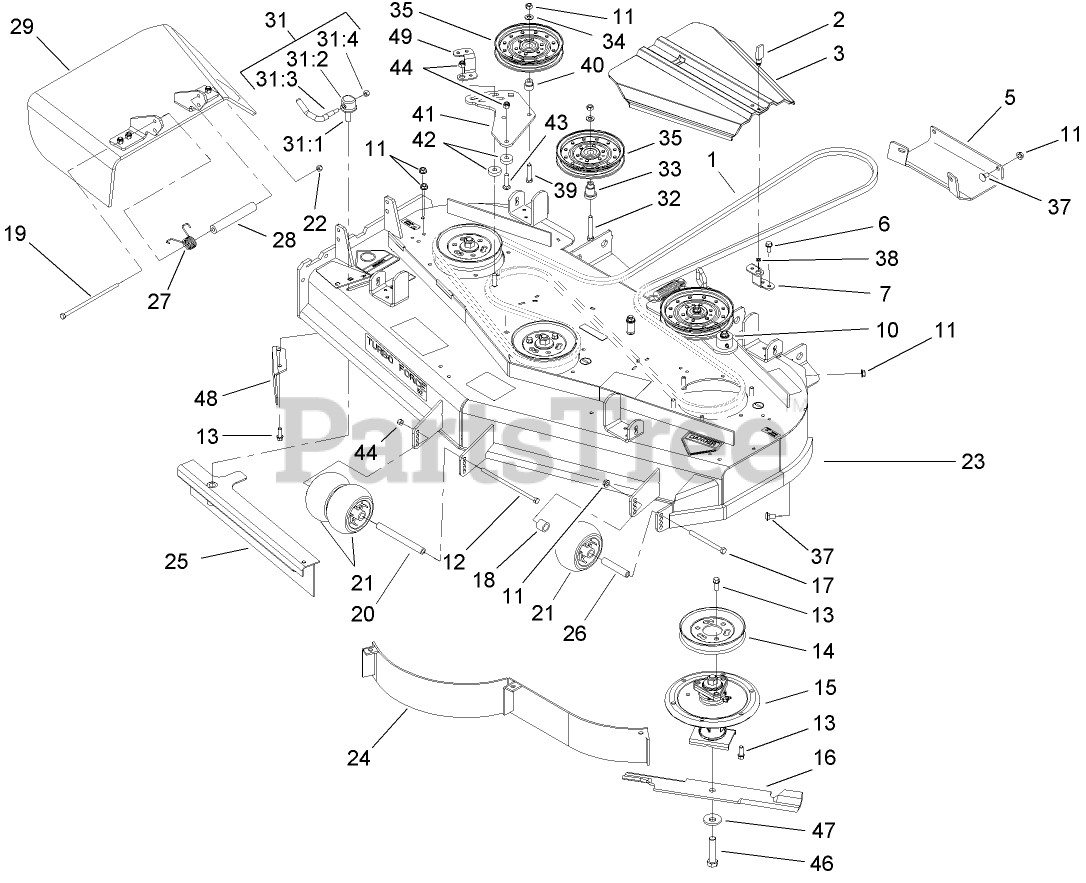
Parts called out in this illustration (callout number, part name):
1	BELT-V
2	LATCH-SWELL
3	COVER-BELT
5	Plate-Skid
6	SCREW-HWHTF
7	BRACKET-COVER, TALL
10	IDLER ASM
11	NUT-HHF, WHIZ
12	SCREW-HH
13	SCREW-HWH
14	PULLEY
15	SPINDLE ASM
16	BLADE-18IN, HI FLOW
17	SCREW-HH
18	TUBE-SPACER
19	SCREW-HH
20	SPACER-WHEEL
21	ROLLER-SCALP, ANTI
22	NUT-LOCK, NI
23	DECK ASM
26	TUBE-SPANNER
27	SPRING-TORSION
28	SPACER
29	RUBBER DEFLECTOR ASM
31	LEVER ASM
31:1	Screw-Lock
31:2	CAP-LOCK
31:3	Lever-Lock
31:4	NUT-LOCK, NI
32	SCREW-HH
33	MOUNT-PULLEY
34	WASHER-FLAT
35	Idler-Flat
37	SCREW-CARR
38	WASHER
39	SCREW-HH
40	BUSHING-IDLER
41	PLATE-IDLER
42	Spacer
43	SCREW-CARR
44	NUT-LOCK, NI
46	Screw-Cap
47	Washer-Blade Bolt, Heavy
48	BAFFLE-DISCHARGE
49	BRACKET-COVER, SHORT
